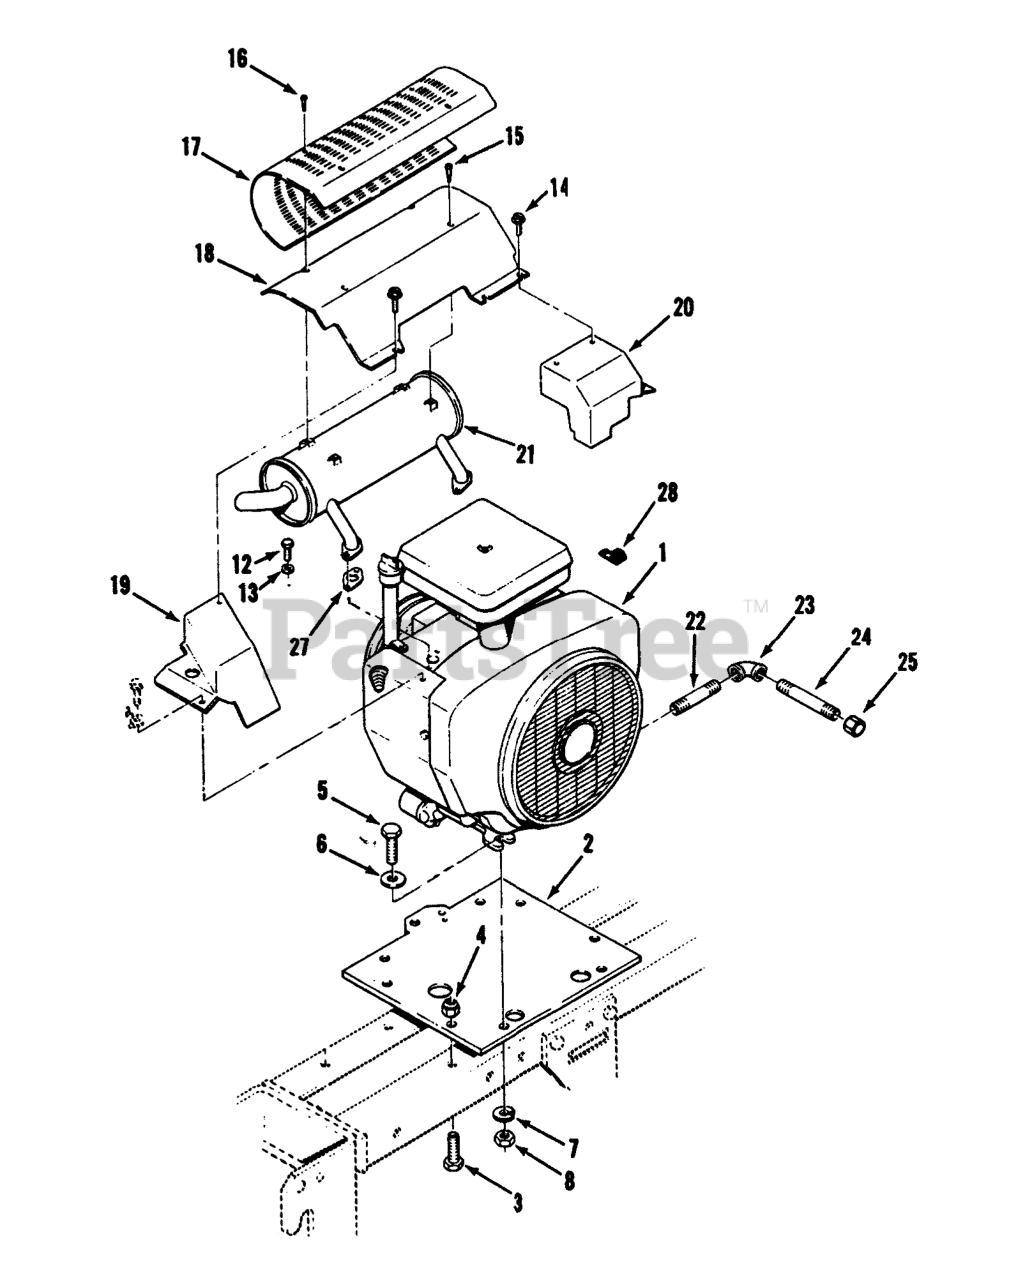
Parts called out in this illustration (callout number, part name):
1	Engine-20HP
2	PLATE-ENGINE B
3	SCREW-HH
4	NUT-LOCK, NI
5	SCREW-HH
6	WASHER-FLAT
7	WASHER-LOCK
8	NUT-HEX
12	SCREW-HH
13	WASHER-LOCK
14	HEX WASHER HD SCREW
15	Screw
16	SCW 10-24 STAINLESS
17	SHIELD
18	Air Deflector
19	COVER EXHAUST LH
20	COVER EXHAUST RH
21	MUFFLER-EXHAUST
22	NIPPLE-PIPE
23	ELBOW 3/8 90 DEG
24	PIPE-NIPPLE 3/8 X 4"
25	Cap
27	Gasket-Exhaust
28	CLIP
